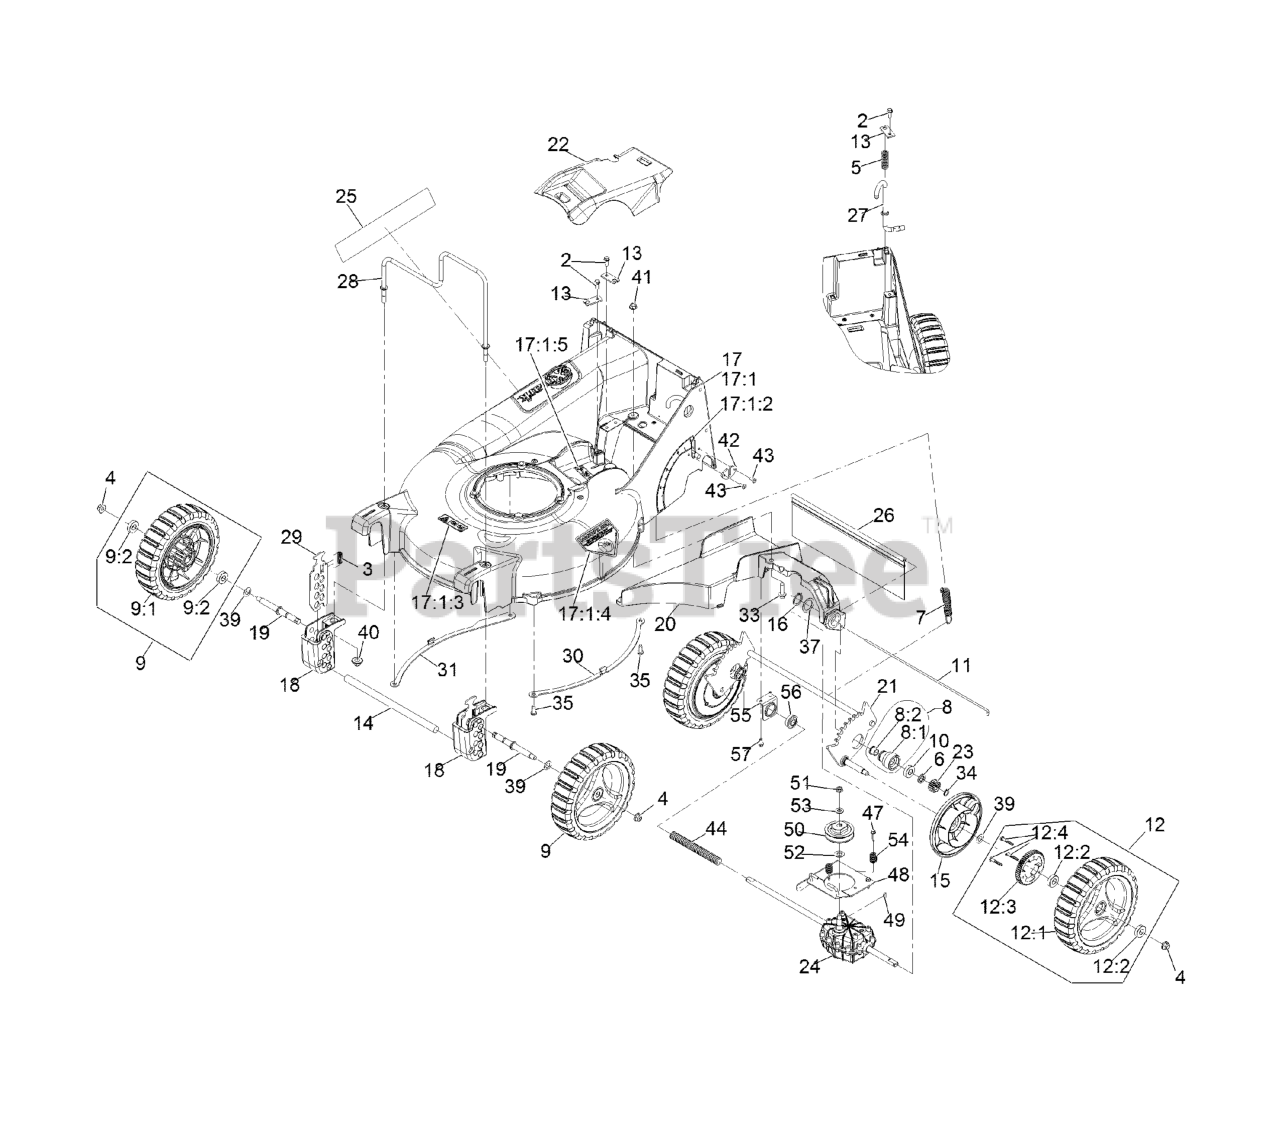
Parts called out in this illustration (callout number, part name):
2	SCREW-HWH
3	SPRING-COMPRESSION
4	NUT-HF, NI
5	SPRING-COMPRESSION
6	SPACER-BUSHING
7	SPRING-EXTENSION
8	HOUSING ASM
8:1	HOUSING-BEARING
8:2	BEARING-FLANGE
9	WHEEL ASM, 9" W/BEARINGS
9:1	WHEEL ASM, 9
9:2	BEARING-BALL
10	BEARING-BALL
11	ROD,SHIELD
12	WHEEL ASM, 9 W/GEAR
12:1	WHEEL ASM, 9
12:2	BEARING-BALL
12:3	GEAR-WHEEL, 52T
12:4	STUD-DRIVE
13	BRACKET,MOUNT
14	ROD,BUMPER
15	COVER,GEAR
16	RING-RETAINING
17	DECK-ASM, COM21 BOXED
17:1	Deck W/Decals
17:1:2	DECAL-HEIGHT OF CUT
17:1:3	DECAL-WARNING, BLADE
17:1:4	DECAL-DANGER
17:1:5	DECAL-DANGER
18	BLOCK,FRONT QUADRANT
19	AXLE-WHEEL
20	BRACKET-TRANSMISSION AND
21	WLD,REAR AXLE P21
22	COVER,BELT
23	GEAR-PINION, 15T
24	TRANSMISSION-HD, 4.5/1
25	DECAL-COMM 21 X-SERIES
26	SHIELD-TRAILING P21
27	ROD-HEIGHT ADJ P21
28	GUARD,ENGINE
29	PLATE, FRONT HEIGHT
33	SCREW-HWHTF
34	RING-RETAINING
35	SCREW-BHTF
39	WASHER-PLAIN
40	Nut-Nyloc 3/8-16 Flg
41	NUT-HF, NI
42	PLATE,WEAR
43	RIVET-BLIND
44	COVER-SHAFT-DRIVE
47	SCREW-SPECIAL
48	TRANSMISSION PLATE ASM
49	KEY-WOODRUFF
51	NUT-HEX
52	WASHER-THRUST
53	WASHER-FLAT
54	SPRING,COMPRESSION
55	MOUNT-BEARING
56	BEARING-BALL
57	SCREW-HWH
